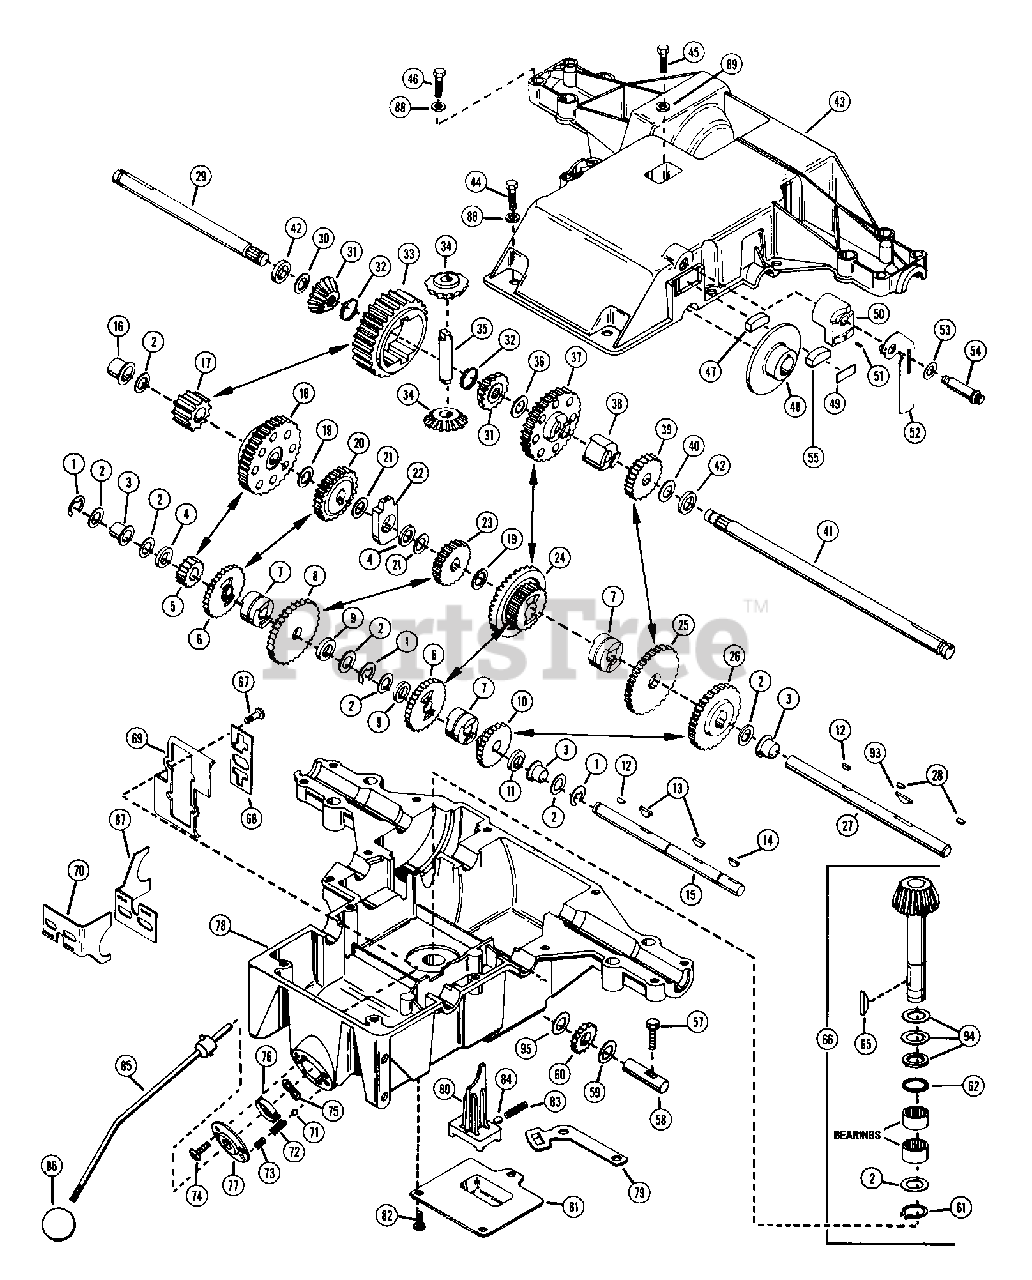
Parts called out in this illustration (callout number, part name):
1	RG-RTNG-EXT .625X.042
2	SHIM KIT
3	FLANGE BEARING
4	SPACER .630X1.000X.110
5	SPUR GEAR 13T
6	SPUR GEAR 25T
7	CLUTCH COLLAR
8	SPUR GEAR 30T
9	SPACER .633X1.00X.260
10	SPUR GEAR 20T
12	KEY-WDRF .125X.500X.203 SAE 3
13	KEY-FTHR FOOTE #3068
14	KEY-WDRF .188X.625X.25 SAE 61
15	INTERMEDIATE SHAFT
16	FLANGE BEARING
17	GEAR ASSY 12T
18	SPUR GEAR 37T
19	WASHER
20	SPUR GEAR 25T
22	SHAFT SUPPORT ASSY
23	SPUR GEAR 20T
24	BEVEL GEAR ASSY
25	SPUR GEAR 33T
26	SPUR GEAR 30T
27	DRIVE SHAFT
28	KEY-WDRF FOOTE #3311
29	L H AXLE
30	SHIM KIT
31	SPLINED MITER GEAR 15T
32	RG-RTNG-EXT .625X.035
33	SPUR GEAR 32T
34	MITER GEAR 15T
35	CROSS SHAFT
36	WSHR-HDND-THRST .758X1.23X.031
37	SPUR GEAR 35T
38	GEAR LOCK
39	SPUR GEAR 22T
40	WSHR-FL-STL .760X1.250X.060 PL
41	R H AXLE
42	SEAL J.B.FOOTE #5130
43	LOWER HOUSING
44	BLT-HEX .25-20X1.00 GR2
45	SCR-MCH 12-24X.62 HEXWH
46	BLT-HEX .25-20X1.25 PL GR5
47	BRAKE JAW FRICTION PUCK
48	BRAKE DISC
49	SPACER - FLAT .045 THICK
50	BRAKE JAW ASSY
51	SCR-SET 8-32 FOOTE 1606
52	ACTUATING LEVER ASSY
53	WSHR-FL-STL .505X.750X.006
54	SHOULDER BOLT
55	FRICTION PAD
56	SG-COMP J.B. FOOTE
57	SCR-MCH 10-24X1.00 HEX PL
58	IDLER SHAFT
59	WSHR-FL-STL .505X1.000X.020
60	IDLER GEAR ASSY
61	RG-RTNG-EXT .625X.035
62	O-RING .612X.805X.102
65	KEY-WDRF .188X.75X.313 SAE 9
66	INPUT SHAFT ASSY KIT
67	BLT-HEX .25-28X.75 PL GR5
68	LOCK-OUT PLATE
69	FORK PLATE SUPPORT
70	SHIFTER FORK
71	DETENT BALL
72	SG-COMP ??X??X?? FOOTE
73	SCR-SET .25-20X.38 SKHCUP OH
74	SCR-MCH 10-24X.50 SLTR PL
75	WAVE WASHER .760X1.062X.105FH
76	NYLON INSERT
77	NYLON COVER
78	UPPER HOUSING
79	HI-LO SHIFT LEVER
80	SELECTOR FORK KIT
81	HI-LO COVER PLATE
82	SCR-MCH 8-32X.50 SLTR PL
83	SG-COMP .035X.186X.702
84	DETENT PIN
85	SHIFT LEVER ASSY
86	SHIFT BALL
87	SHIFTER FORK
88	WSHR-LK .250X.077 HVY PL
93	KEY-FTHR FOOTE #3068
94	SHIM KIT
95	WASHER
96	WSHR-FL-STL .633X1.000X.041
